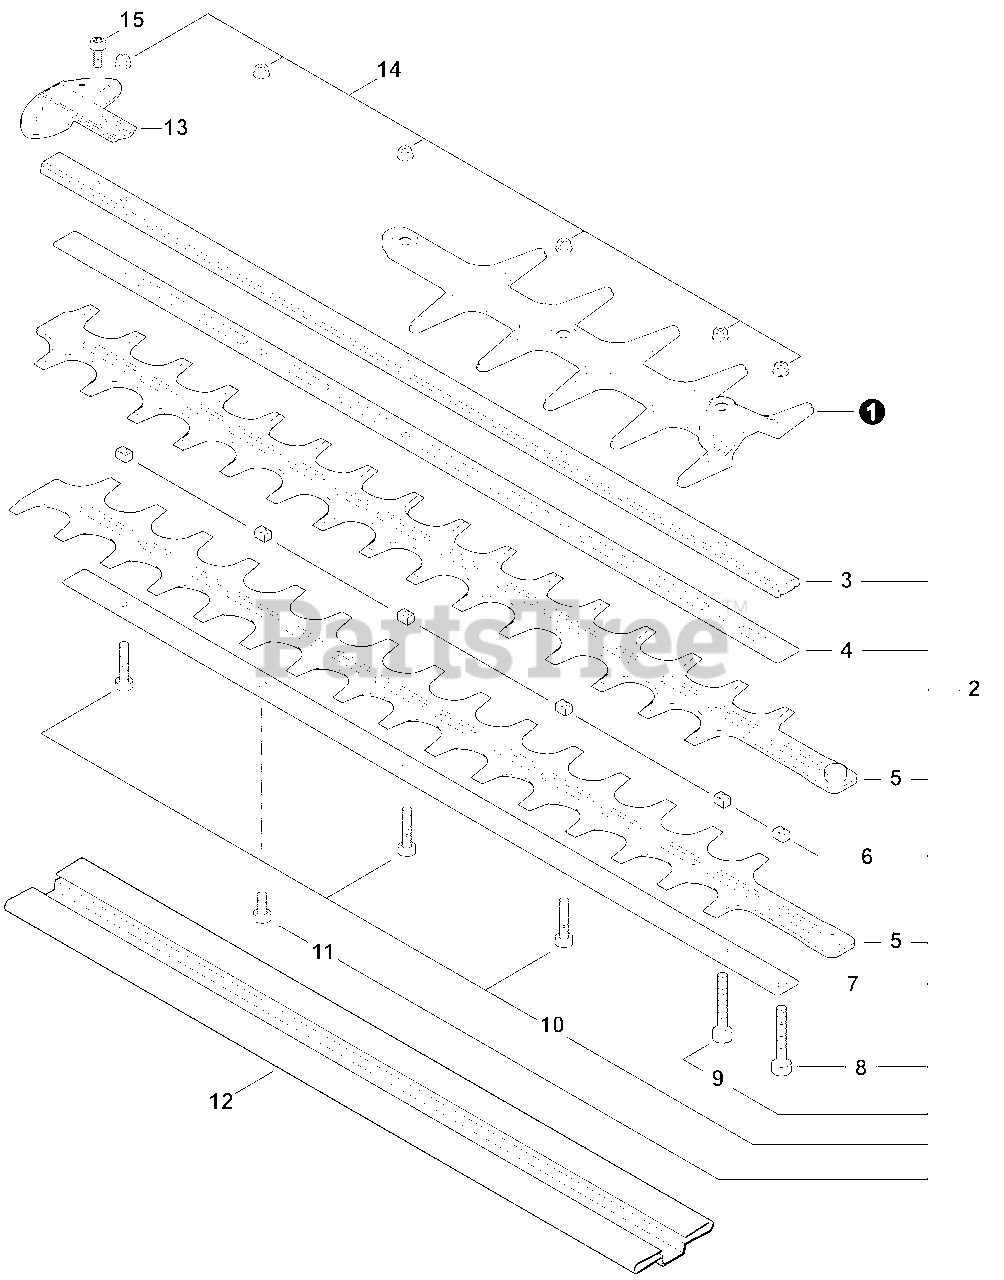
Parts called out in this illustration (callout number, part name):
1	GUARD, CUTTER BLADE
2	CUTTER ASSY, 20"
3	SUPPORT, CUTTER 20"
4	PLATE, CUTTER 20"
5	CUTTER, 20"
6	GUIDE, BLADE 5
7	PLATE, CUTTER 20"
8	BOLT, TORX 5×30
9	BOLT, TORX 5
10	BOLT, TORX 5×25
11	BOLT, TORX 5×20
12	SCABBARD
13	GUARD, TIP
14	NUT, FLANGE M5
15	BOLT, TORX 5×8
